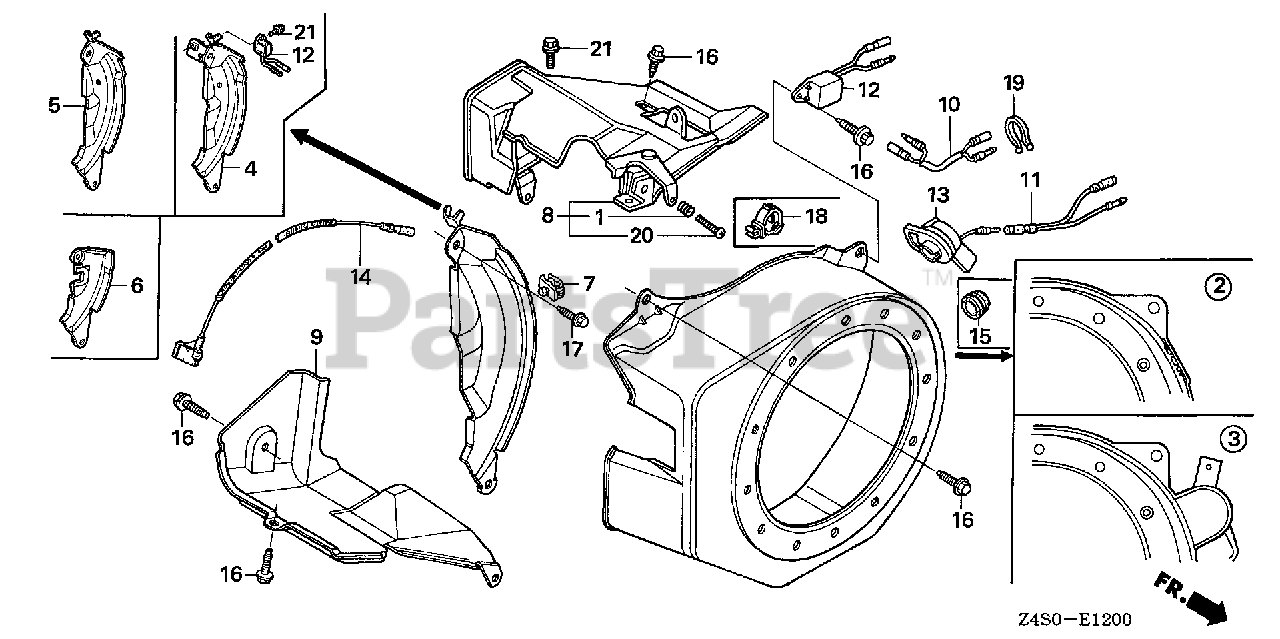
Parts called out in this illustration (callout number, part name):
3	COVER, FAN *R280* (POWER RED)
6	PLATE, SIDE (STARTER MOTOR)
14	WIRE, STOP SWITCH (395MM)
16	BOLT, FLANGE (6X12) (CT200)
17	BOLT, FLANGE (6X25) (CT200)
